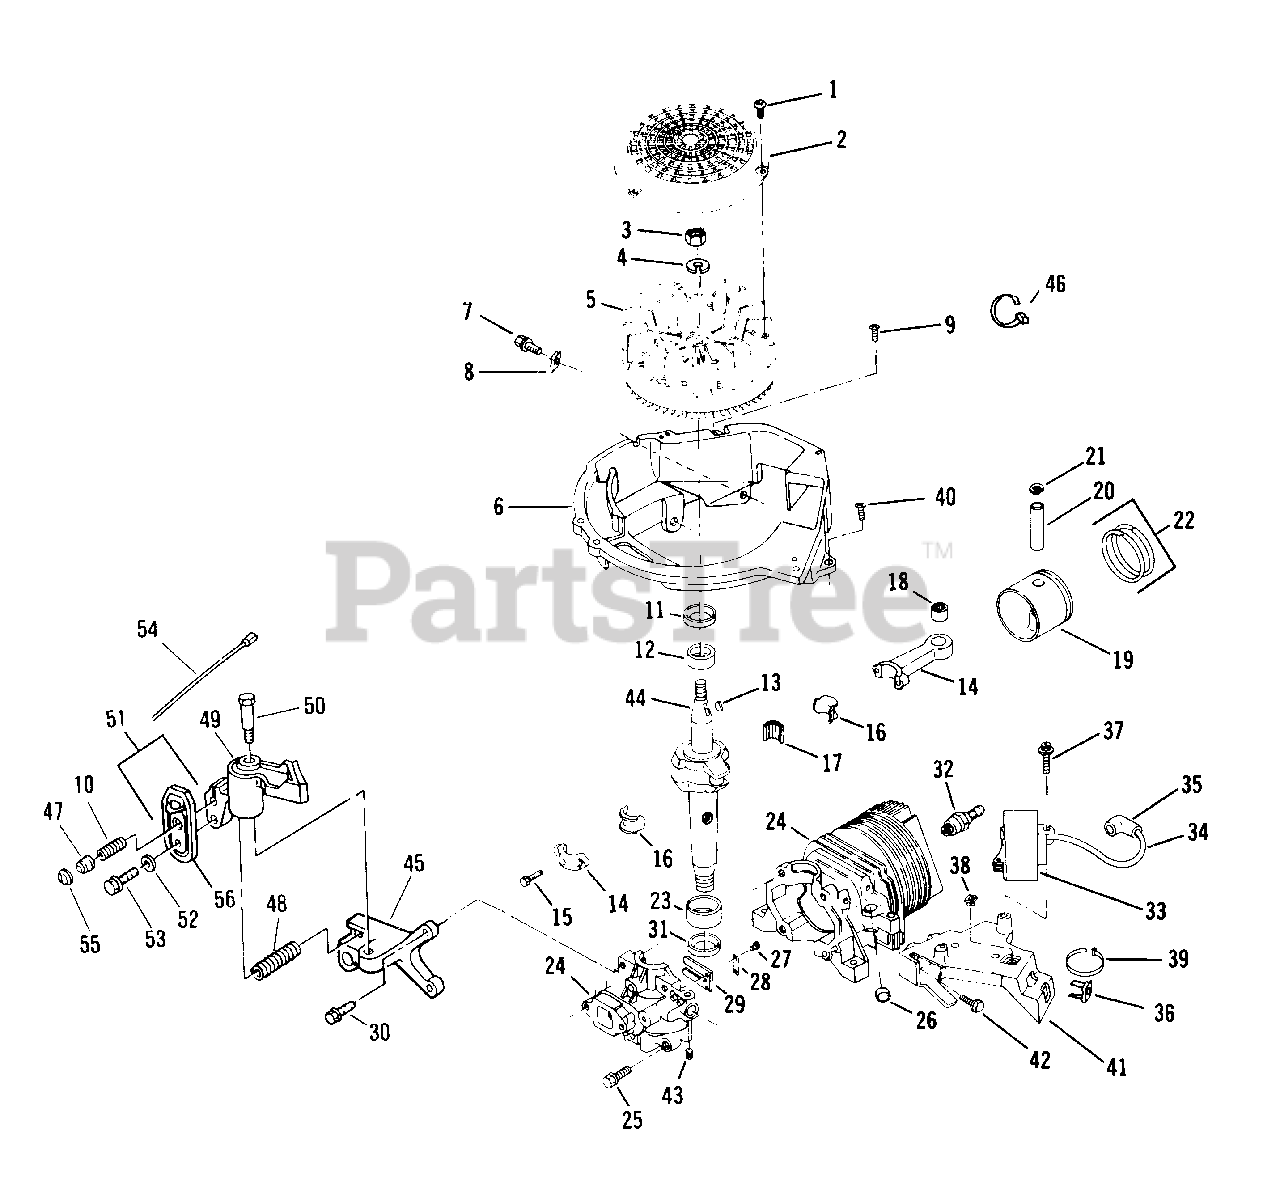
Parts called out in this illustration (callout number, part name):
1	Screw-Flywheel Screen
2	Screen-Flywheel
3	Nut-Flywheel
4	Lockwasher
5	Flywheel Assembly
6	Base-Shroud
7	Screw
8	Clip-"J"
9	Screw
10	Spring-Cable Retainer
11	Oil Seal-Upper
12	Bearing-Main-Upper
13	Key-Flywheel
14	Connecting Rod Assembly
15	Screw-Cap
16	Liner Split
17	Needle Bearing Set
18	Bearing Assembly
19	Piston and Ring Set
20	Wrist Pin
21	Retaining Ring
22	Ring Set
23	Bearing-Main-Lower
24	Cylinder and Crankcase Cover Asy
25	Screw-Cover to Crankcase
26	Plug
27	Screw-Reed to C'case Cover
28	Plate-Reed Hold Down
29	Reed
30	Screw-Brake Mounting Bkt.
31	Oil Seal-Lower
32	Spark Plug
33	C.D. Ignition Module and Lead Asy
34	High Tension Lead & Lwr. Asy.
35	Spring Terminal
36	Grommet
37	Screw-C.D. Mounting
38	Grommet-C.D. Bracket
39	Tie Strap
40	Screw-Shroud Base to C.D. Brkt.
41	Bracket-C.D. Mounting
42	Screw
43	Set Screw-Starter Assembly
44	Crankshaft
45	Bracket-Brake
46	Tie Strap
47	Actuator-Brake Lever
48	Spring-Brake
49	Brake Assembly
50	Bolt-Shoulder
51	Switch Assembly
52	Washer
53	Screw
54	Lead Assembly
55	Retainer
56	Case Assembly-Only
